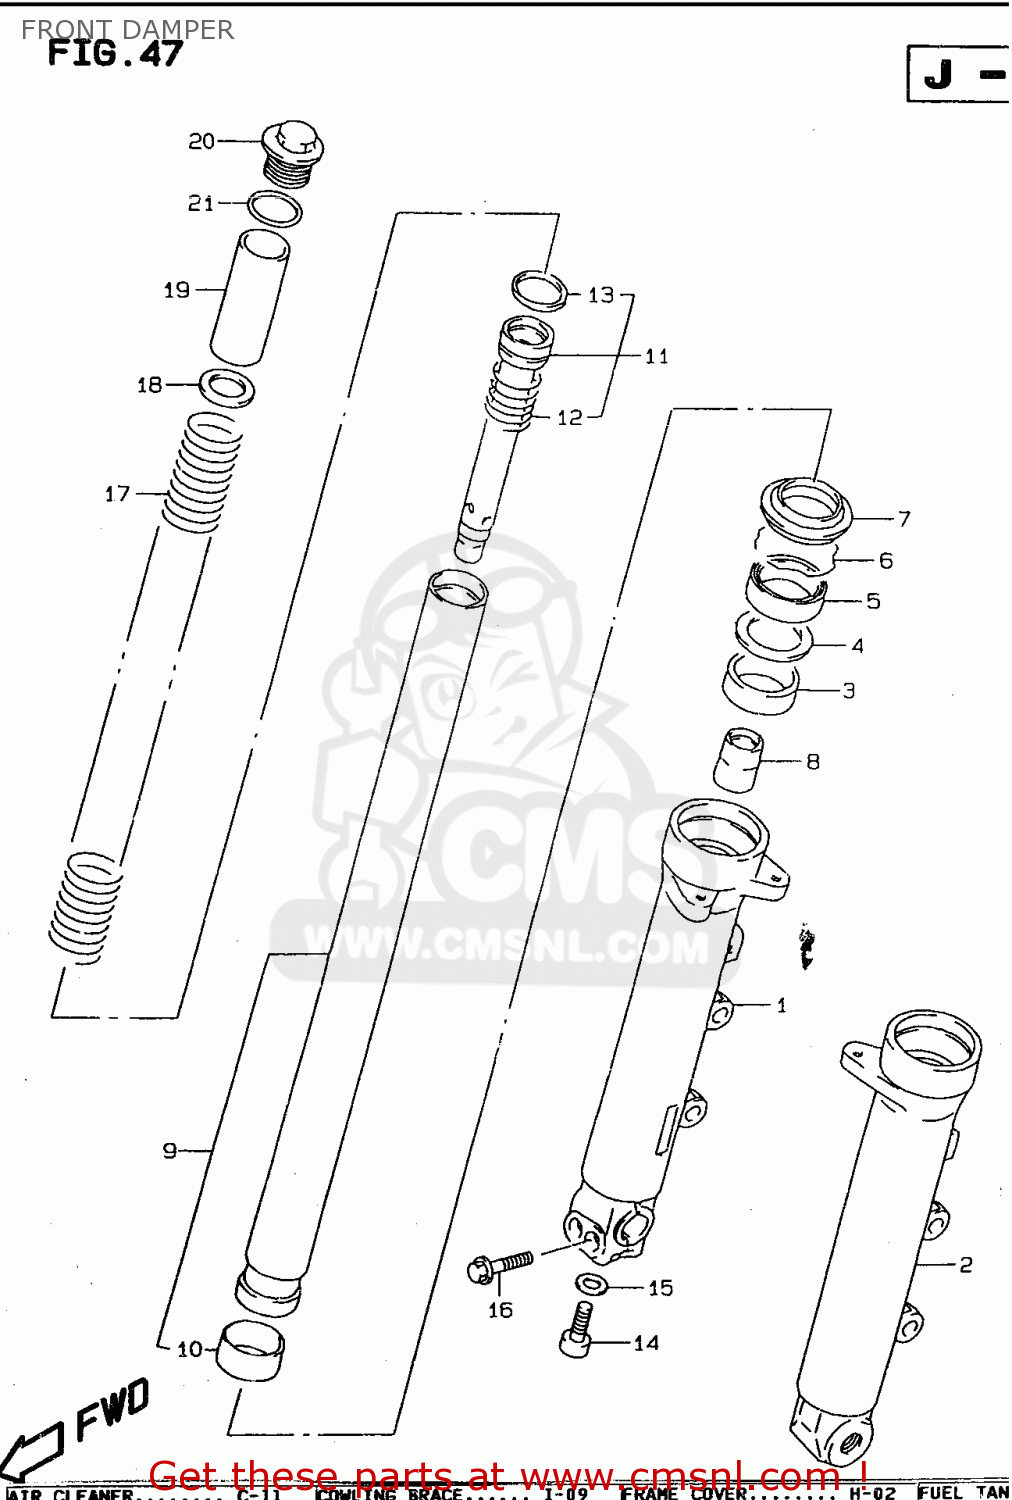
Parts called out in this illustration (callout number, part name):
1	TUBE,OUTER,R
2	TUBE,OUTER,L
3	METAL,SLIDE
4	WASHER,FORK OIL SEAL
5	SEAL,OIL
6	RING,OIL SEAL STOPPER
7	SEAL,DUST
8	PIECE,OIL LOCK
9	TUBE,INNER
10	PISTON
11	CYLINDER
12	SPRING,REBOUND
13	RING,PISTON
14	BOLT,FORK CYLINDER(10X25)
15	GASKET (NAS)
16	BOLT
17	SPRING,MAIN
18	WASHER(22.5X35.9X1.6)
19	SPACER,SPRING
20	CAP,FORK
21	O RING(D:3.5,ID:31.7)
